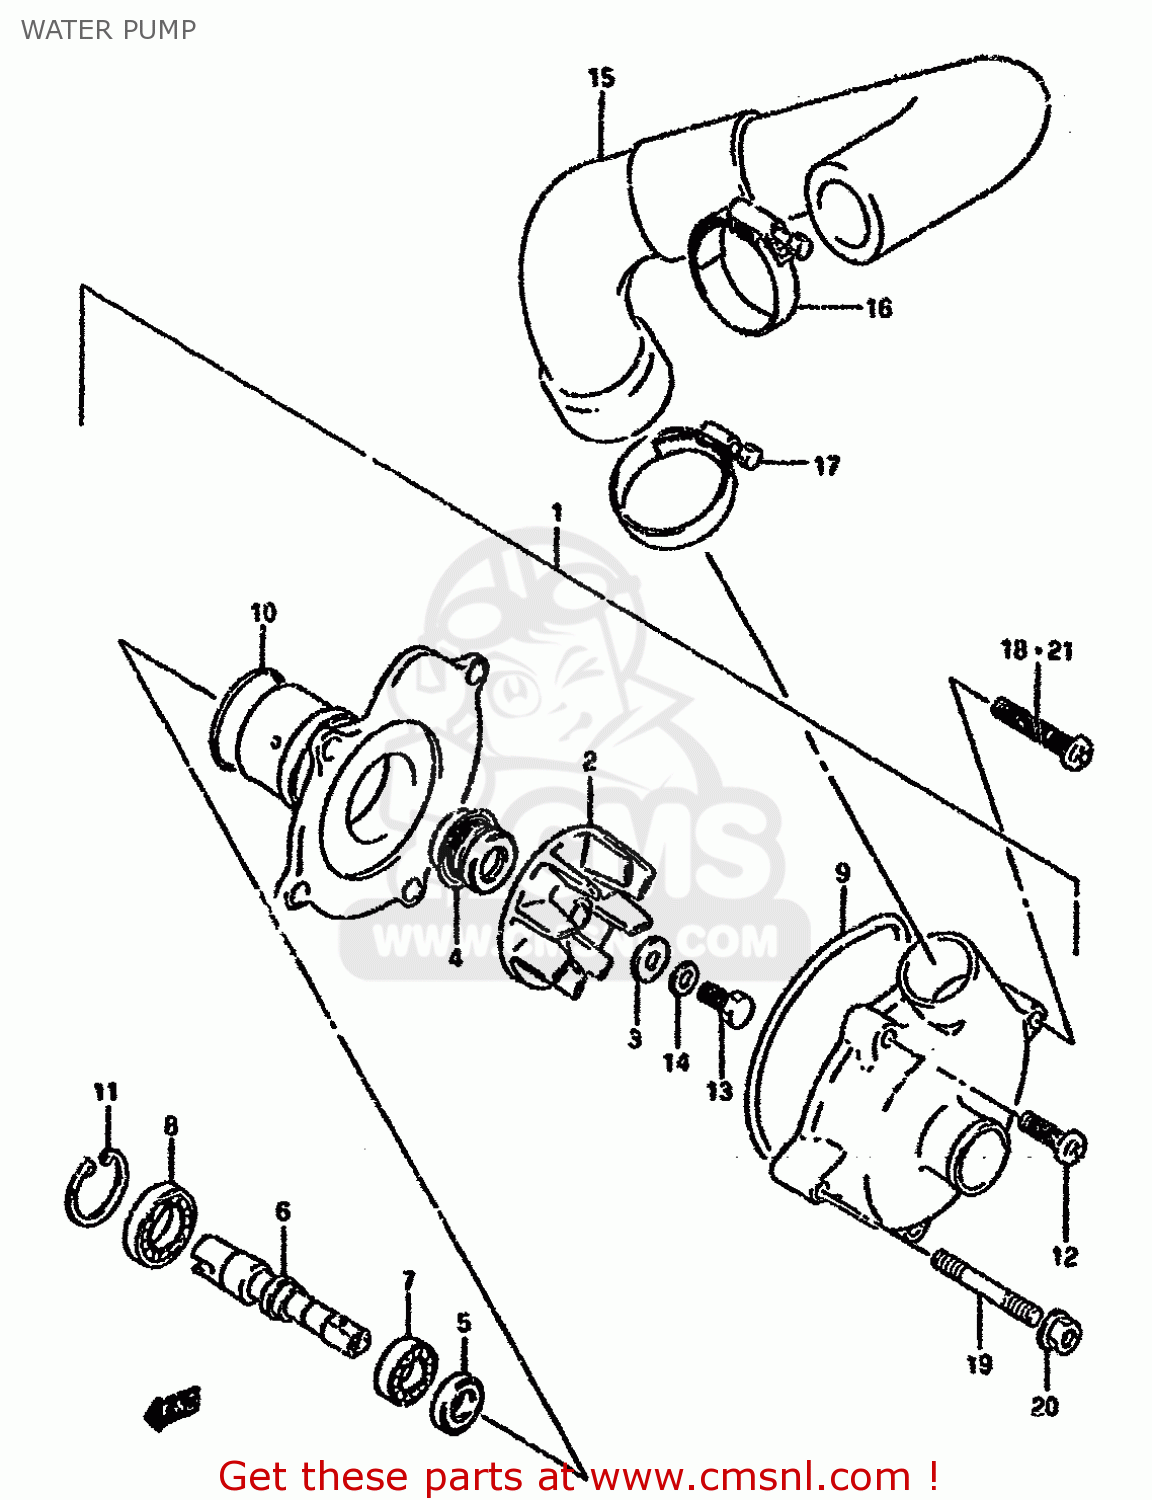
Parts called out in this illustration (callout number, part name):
1	PUMP ASSY,WATER
2	IMPELLER
3	GASKET(6X15X2.2) (NAS)
4	SEAL,MECHANICAL
5	OILSEAL
6	SHAFT
7	BEARING
8	BEARING(12X28X8)
9	O RING
10	O RING,WATER PUMP HOLDER
11	CIRCLIP
12	SCREW 6X16
13	BOLT(6X13)
14	WASHER
15	HOSE,WATER PUMP,OUTLET
16	CLAMP
17	CLAMP
18	SCREW
19	BOLT,STUD
20	NUT
21	SCREW
